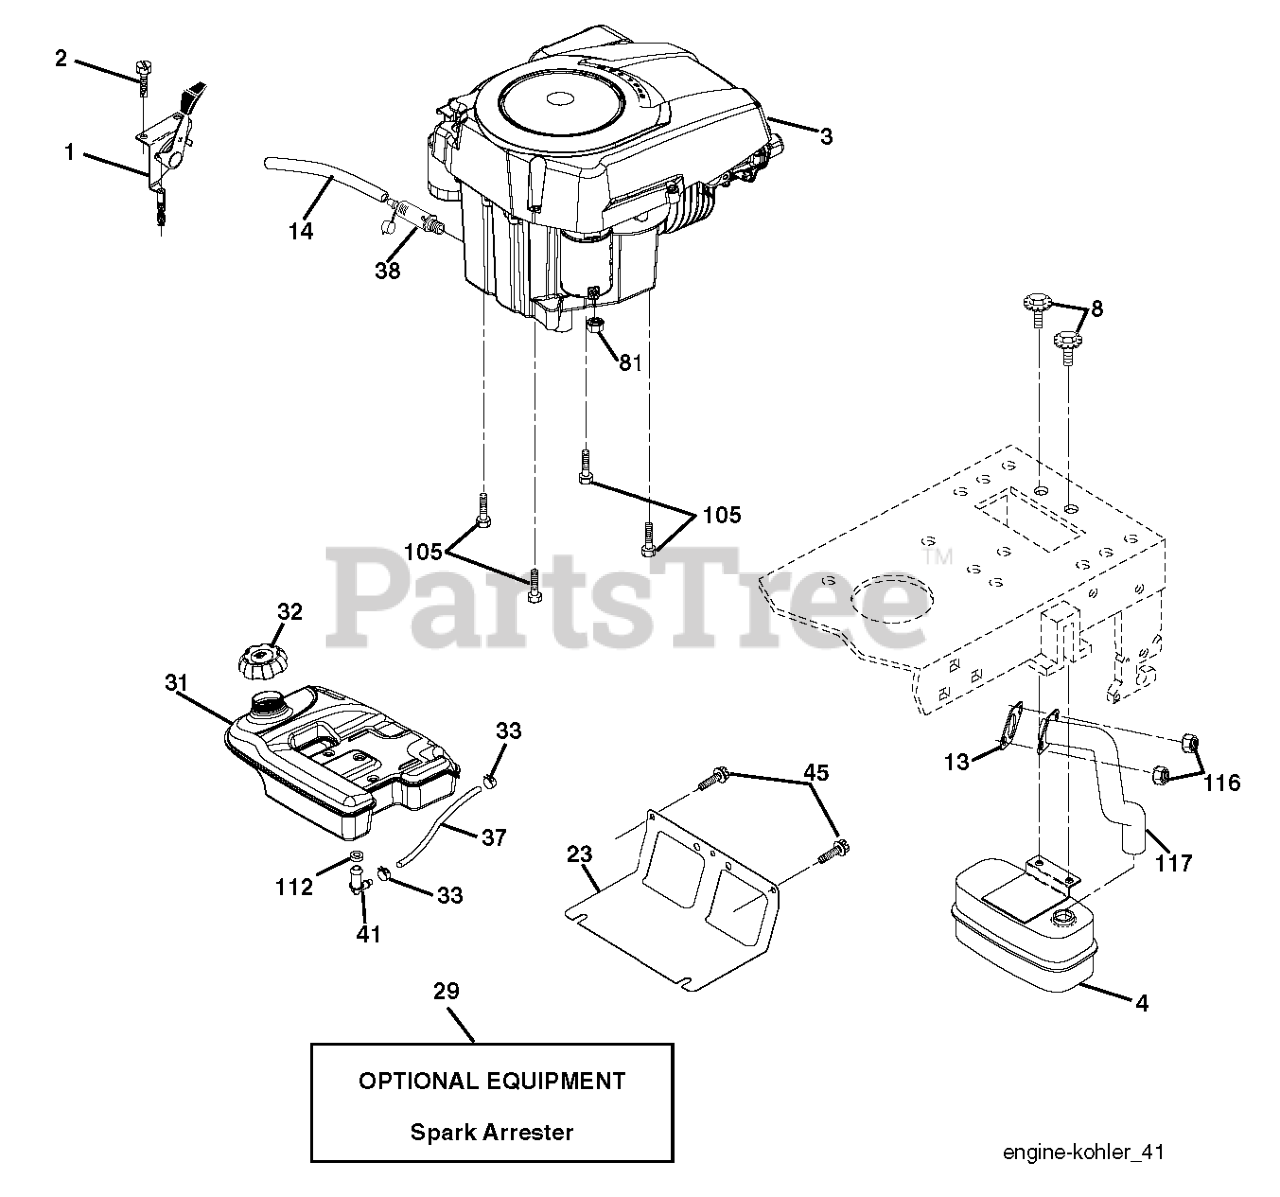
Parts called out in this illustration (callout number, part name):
1	CONTROL.THROTTLE.LT/YT
2	SCREW
4	MUFFLER.SINGLE.CYL.KOHL/B&S
8	BOLT.5/16-18UNCX3/4 W/SEMS.BLK
13	GASKET.EXHAUST.KOHLER
14	TUBE, DRAIN OIL ASM.
23	SHIELD.BROWNING.DBR.GUARD
29	KIT.SPARK ARRESTOR 794945 B&S
31	4.0 REAR FUEL TANK
32	TANK CAP
33	HOSE CLAMP
37	REPL BY 532 00 85-43
38	PLUG DRAIN OIL EASY
41	STEM FUEL TANK
45	SCREW, 3/8-16X3/4
81	NUT
105	SCREW 3/8-16X1
112	BUSHING OUTLET T
116	NUT.HEX.FLANGE.TOPLOCK
117	RP.TUBE.EXHAUST.KOHL.COURAGE
